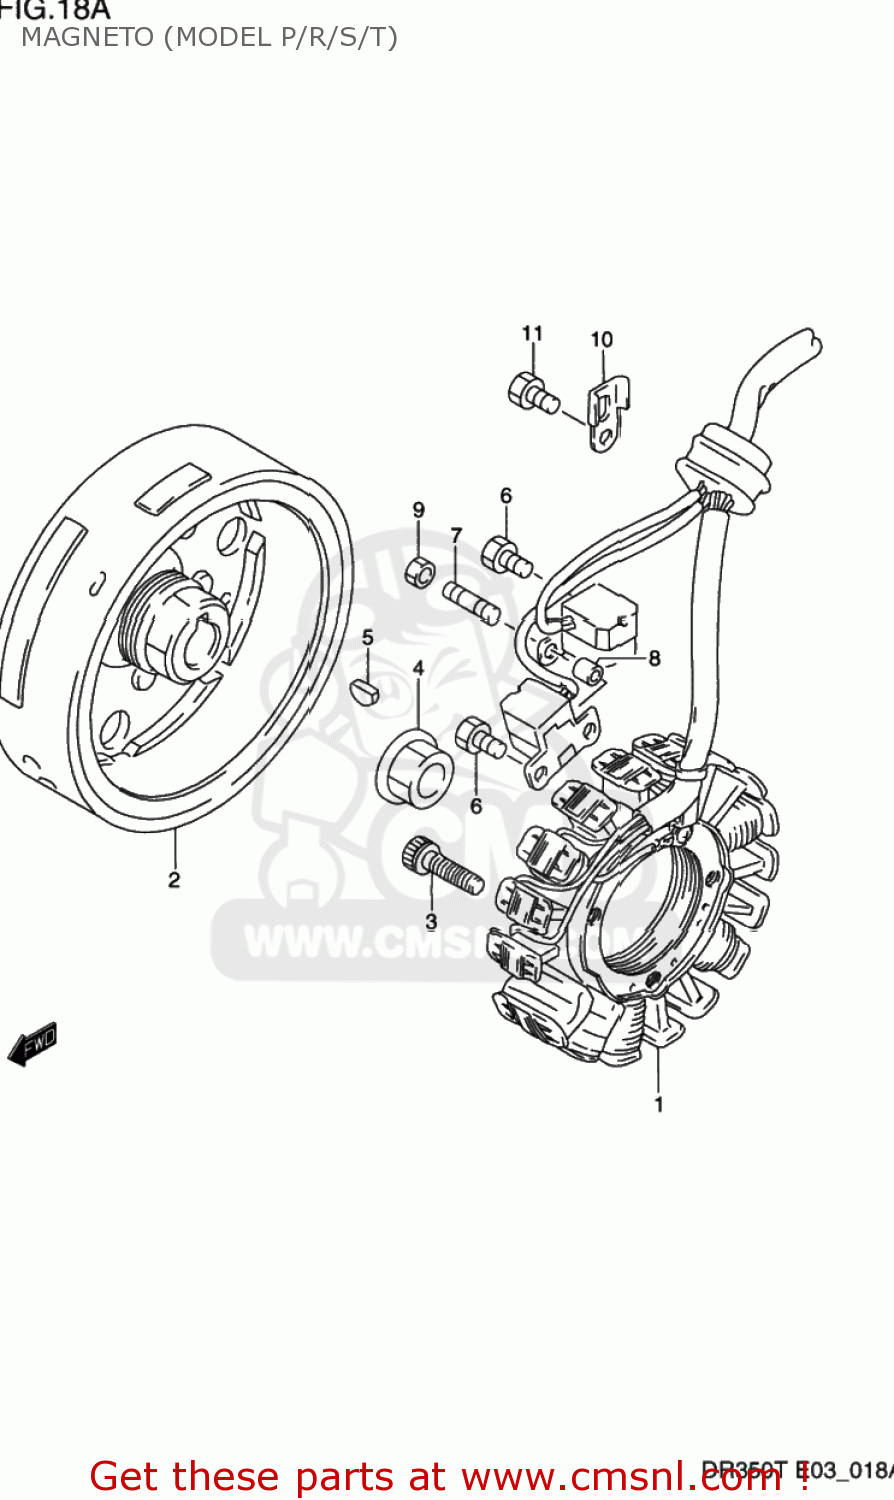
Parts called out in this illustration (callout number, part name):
1	STARTER ASSY
2	ROTOR
3	BOLT
4	NUT
5	KEY
6	BOLT(5X10)
7	BOLT,STUD(5X18)
8	SPACER (5.5X9.5X6.5)
9	NUT
10	CLAMP,GENERATOR LEAD WIRE
11	BOLT(5X10)
